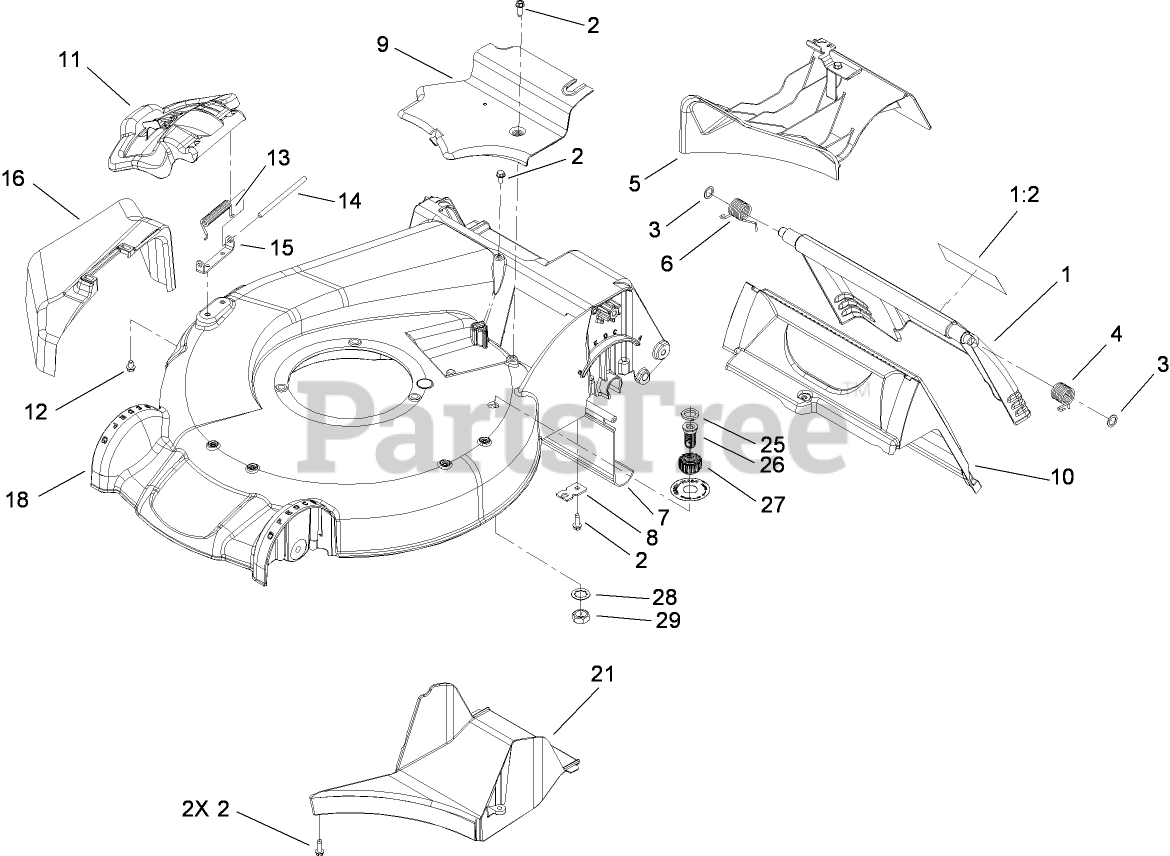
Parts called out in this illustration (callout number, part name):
1	REAR DOOR ASM
1:2	DECAL-WARNING
2	SCREW-HWHTF
3	WASHER-NYLON
4	SPRING-TORSION
5	MULCH PLUG ASM
6	SPRING-TORSION
9	COVER-BELT
11	DISCHARGE DOOR ASM
12	SCREW-HWH
13	SPRING-TORSION
15	BRACKET-COVER
16	CHUTE-DISCHARGE, SIDE
18	HOUSING ASM
21	TUNNEL-DISCHARGE
25	WASHER-SEAL, WASHOUT PORT
26	PORT-WASHOUT
27	COUPLING-HOSE, WASHOUT PORT
28	WASHER-LOCK
29	NUT-JAM
